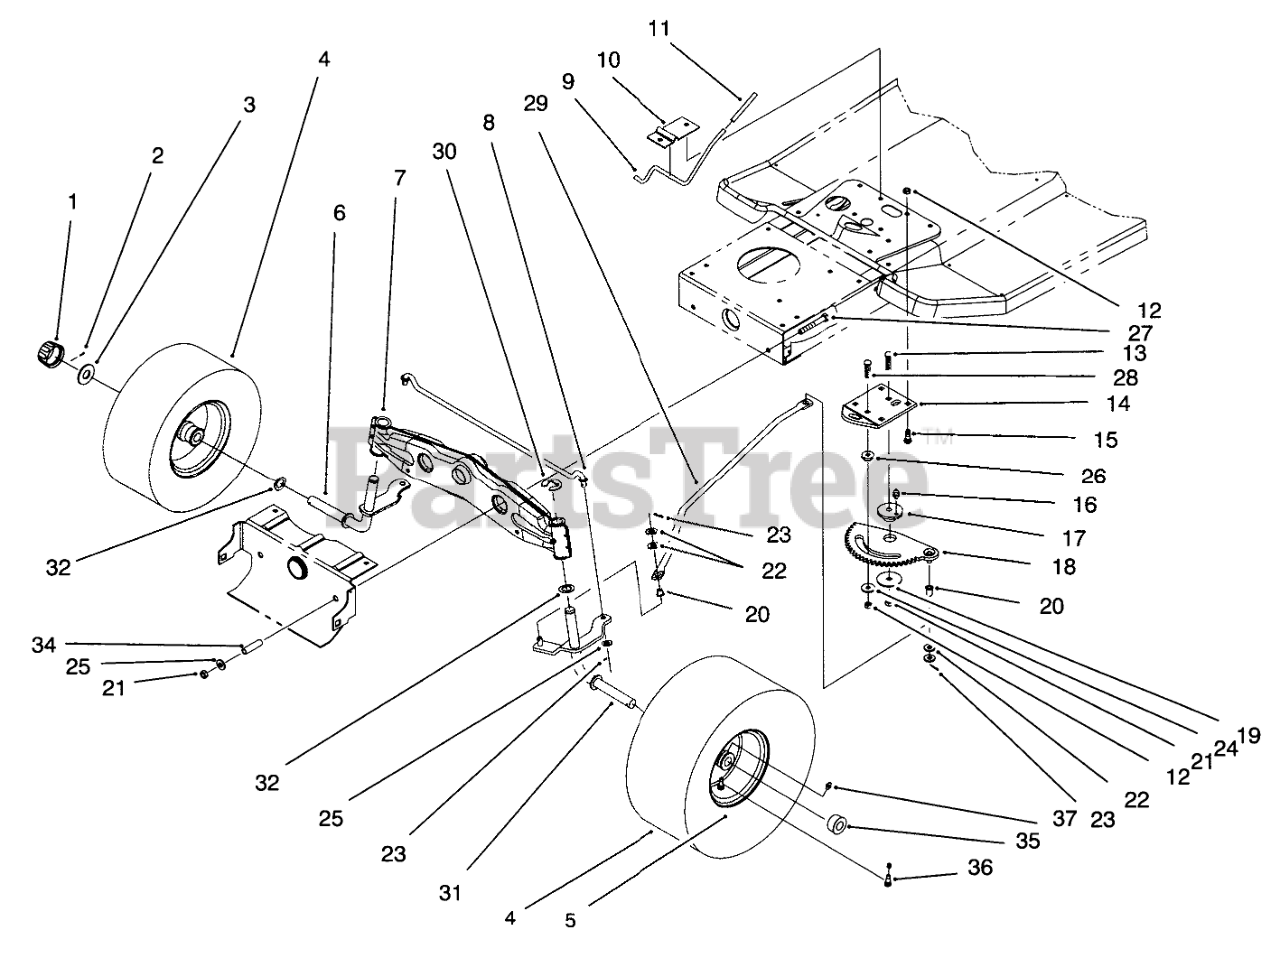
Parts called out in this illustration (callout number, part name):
1	CAP-HUB
2	PIN-COTTER
3	WASHER-PLAIN
4	TIRE 13 X 5.00 X 6
5	RIM ASM
6	Spindle-R.H.
7	Axle-Front
8	TIE ROD-STEERING
9	ROD-BRAKE, PARKING
10	Bracket-Parking Brake
11	GRIP-BRAKE, PARKING
12	NUT-LOCK, NI
13	SCREW-CARR
14	Bracket-Steering Rack
15	BOLT-CARR
16	FITTING-GREASE
17	BUSHING-ECCENTRIC
18	RACK-STEERING
19	WASHER-BEARING
20	BUSHING-FLANGED, NYLON
21	NUT-LOCK, NI
22	WASHER-FLAT
23	PIN-COTTER
24	WASHER-PIVOT
25	WASHER-FLAT
26	SPACER-RACK, STEERING
27	SCREW-HH
28	SCREW-CARR
29	LINK-DRAG
30	E-RING
31	Spindle-L.H.
32	WASHER-THRUST
34	SPACER
35	BEARING-WHEEL
36	STEM-VALVE
37	FITTING-GREASE
